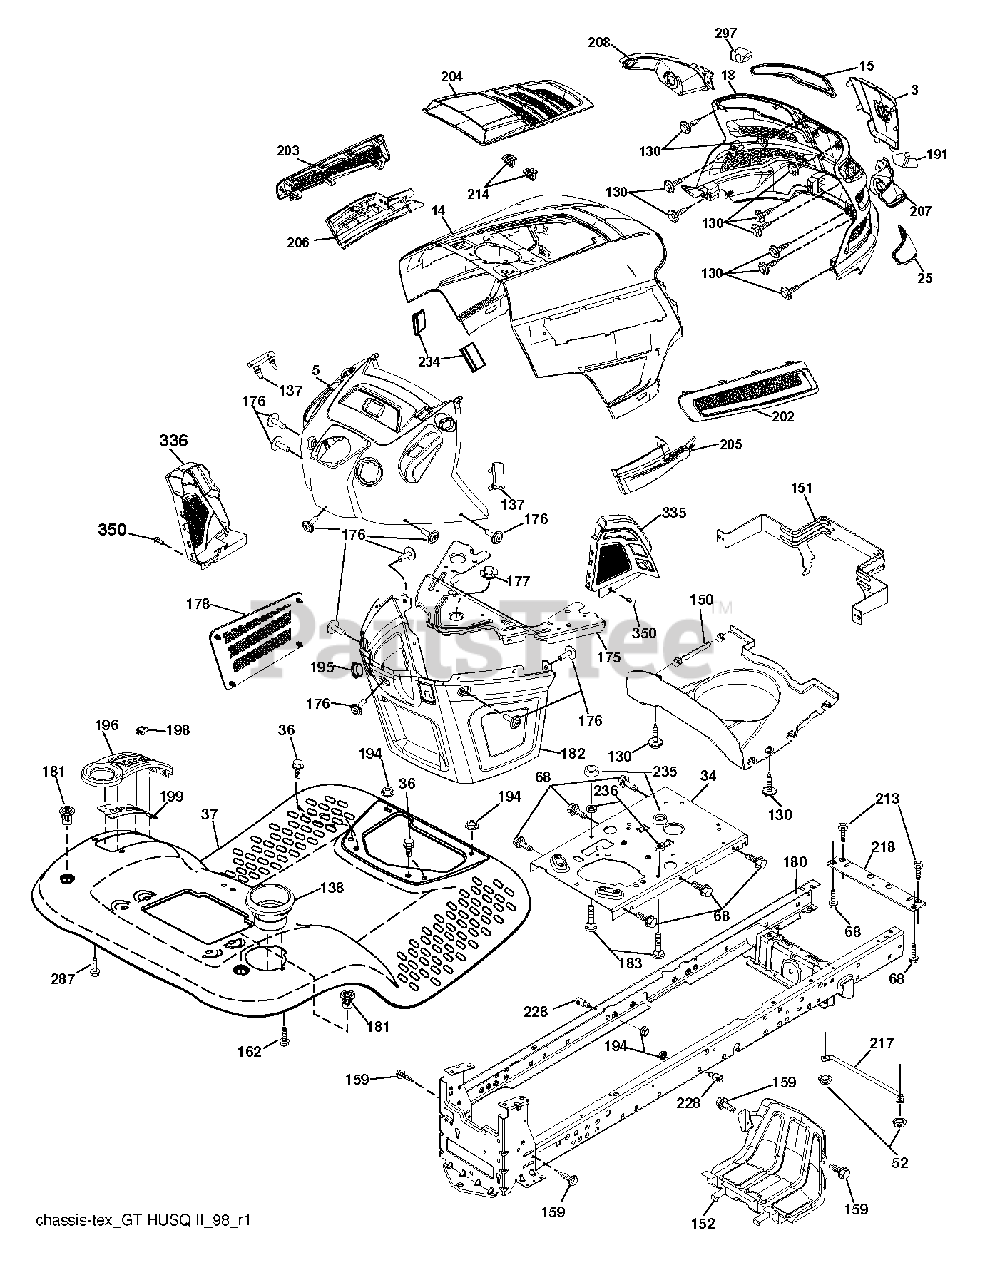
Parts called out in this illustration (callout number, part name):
3	APPLIQUE.SUBASM.GT.HUSQ.II
5	DASH.UPPER.ASSY.GT2.GREY
14	HOOD.ASM.HUSQVARNA.GT.TEX.ORAN
15	LENS.HEADLIGHT.LH.GTII.2011
18	GRILLE.SUBSTRATE.2011.
25	LENS.HEADLIGHT.RH.GTII.2011
34	PLATE.ENGINE.WELDED.CHASSIS
36	SCREW 5/16"
37	FENDER.TLT.PDL.CNTRL.W/CPH.ORG
52	LOCKNUT
68	SCREW LT
130	SCREW.#10 X 0.750.BOS
137	BUMPER DASH
138	HOLDER.CUP.LT.GREY
150	AIR.DUCT.GTV.BLACK
151	BRACKET.PIVOT.HOOD.GT.HUSQ.II
152	SHIELD.BROWNING.PNT.GT.V2
159	SCREW, 3/8-16X3/4
162	SCREW.HI-LO.CONSOLE
175	PLATE.CROSSMEMBER.HUSQ
176	SCREW.#10-24X5/8.RN.QU
177	BUSHING, STEERING
178	CARGO.ASM.NET.TXGT.W/C
180	CHASSIS
181	BUSHING.MNT.FEND.CRGO.TEX.49
182	DASH.LOWER.COMMON.12V.ADAPTOR
183	BOLT.5/16-18X1-1/4 FULL THD
191	INSERT.REFLECTIVE.RH.HUSQ.GTII
194	NUT LOCK HEX FLANGE 5/16-18
195	PLUG.HOLE.DASH.LOWER.12V.BLK
196	DECKLFT.CONSOL FULL ASSM GREY
198	INDICATOR.DECK.LIFT.RED
199	PLATE.DECK.LIFT.HUSQ.LT
202	VENT.SIDE.RH.GT.HUSQ.II.
203	VENT.SIDE.LH.GT.HUSQ.II.498
204	VENT.TOP.HUSQ.GT2
205	SIDE.TRIM.RH.GT.HUSQ.II
206	SIDE.TRIM.LH.GT.HUSQ.II.GRAY
207	BEZEL LIGHT.RH.GT.II.MYLAR
208	BEZEL LIGHT.LH.GT.II.MYLAR
213	BOLT
214	CLIP.RETAINER.TINNER.
217	ROD.PIVOT.HOOD
218	X-PIECE.HOOD.STOP.NON/
228	STUD.FASTNER.W/ANTI-ROTATE
234	BUMPER.HOOD.TEX.HUSQVARNA
235	SPACER FENDER
236	NUT.CENTERLOCK.5/16-
287	SCREW 1/4X20
297	INSERT.REFLECTIVE.LH.HUSQ.GTII
335	COVER.LOWER.DASH.RH.BLACK
336	COVER-LH.LOWER.DASH.GT2.BLACK
350	CLIP.X-MAS.TREE
